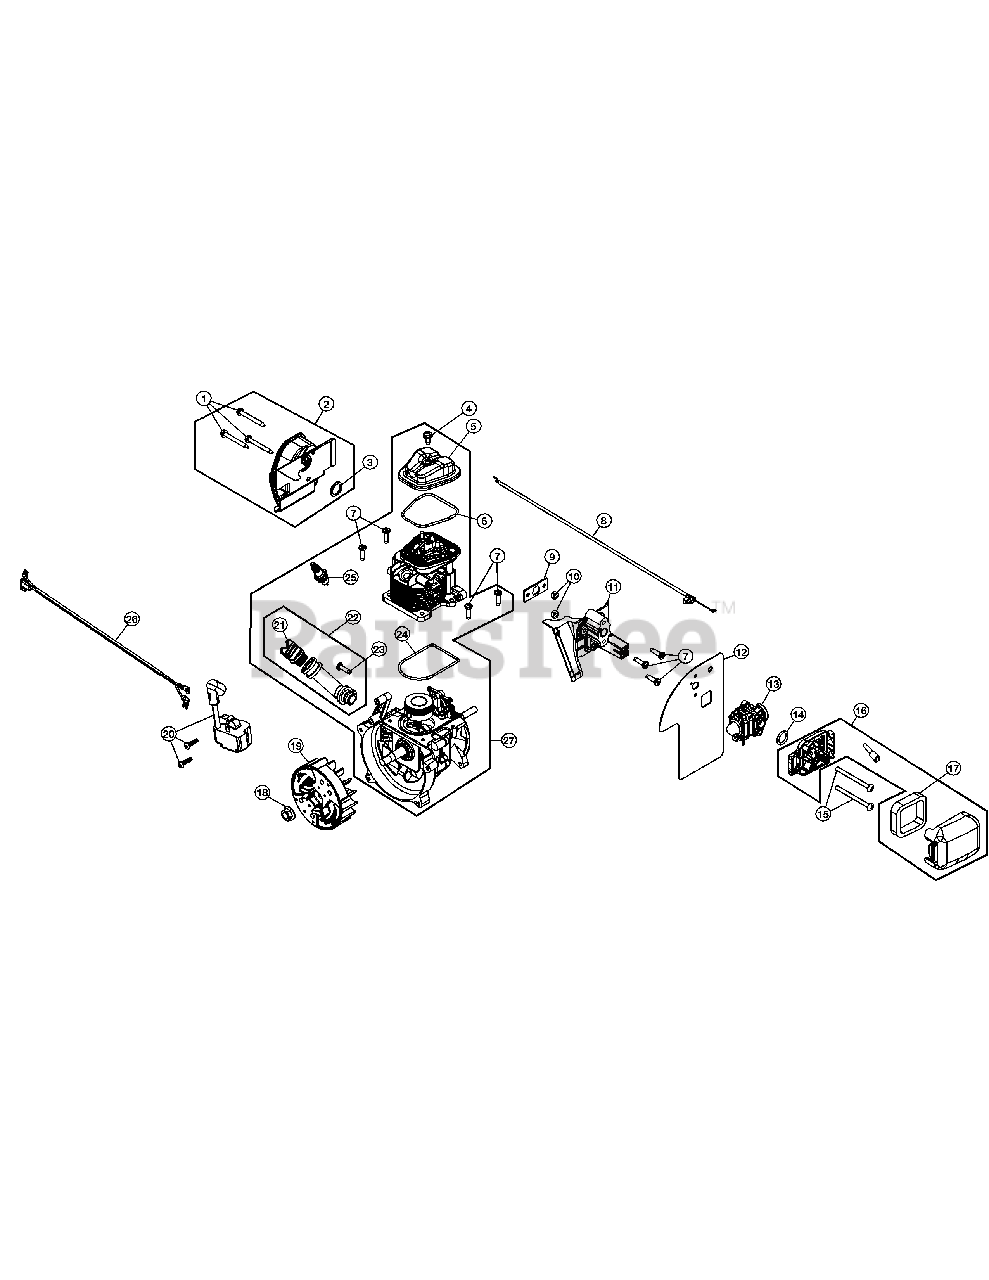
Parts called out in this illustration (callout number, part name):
1	Muffler Screws
2	Muffler Assembly (Incl. 1 & 3)
3	Muffler Gasket
5	Rocker Cover
6	O-Ring
7	Screw
8	Throttle Cable
9	Insulator Gasket
11	Insulator
12	Carburetor Gasket
13	Carburetor
14	Carburetor O-Ring
16	Air Cleaner Assembly (Incl. 17)
17	Air Filter
19	Flywheel Assembly
20	Module
21	Oil Plug
22	Oil Fill Tube (Incl. 23)
24	O-Ring
25	Spark Plug
26	Lead Wire
27	Shortblock Assembly (Incl. 4-7 & 21-25)
